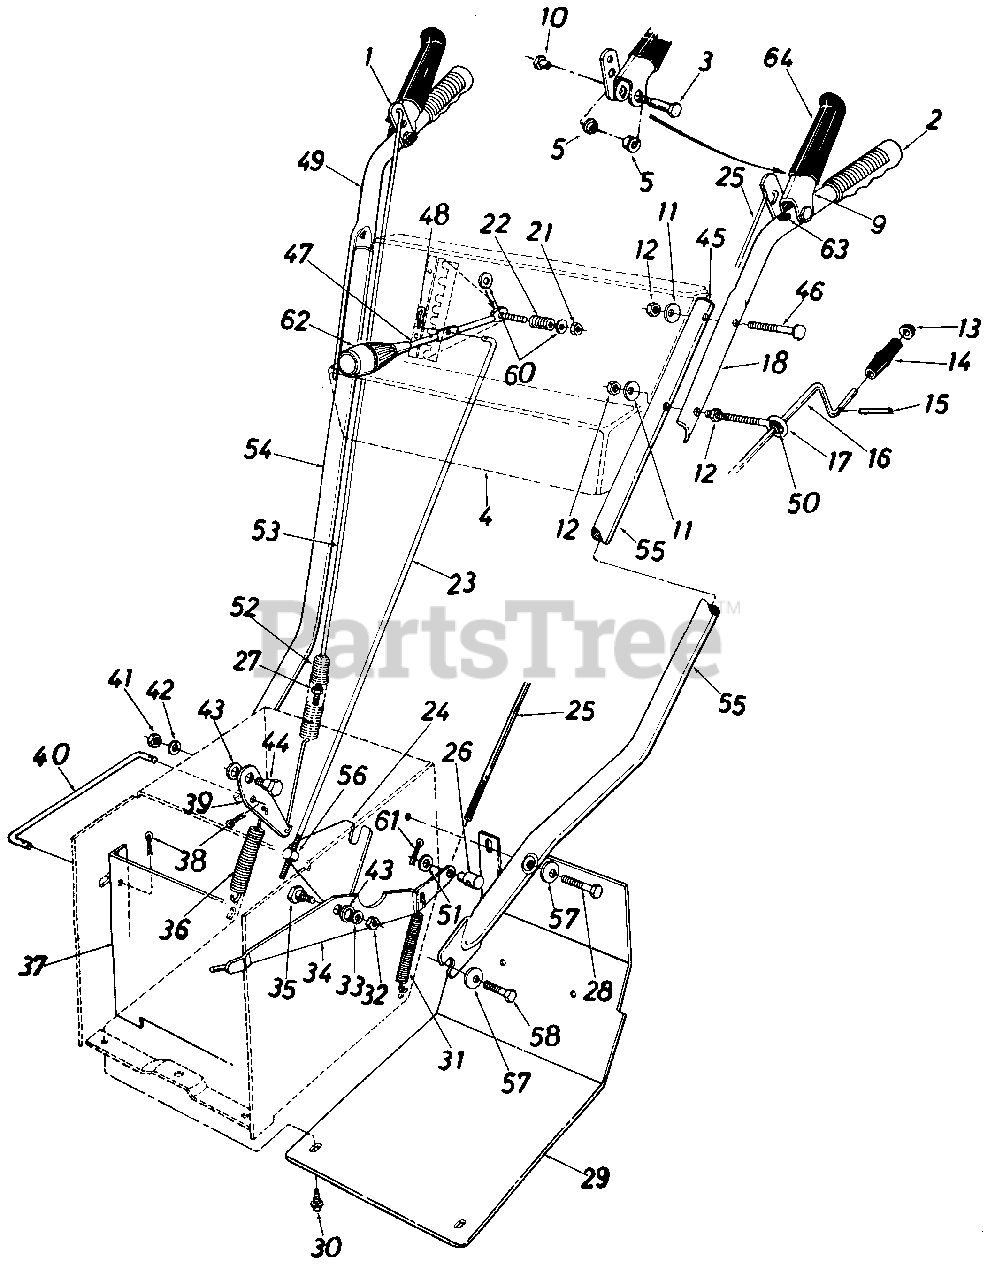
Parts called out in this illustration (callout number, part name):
1	Clutch Grip Ass'y.-R.H.
3	Shoulder Bolt .374 Dia. x 1.375" Lg.
4	Handle Panel Ass'y.
5	Hex Flange Plastic Bearing .380" I.D.
9	Clutch Grip Ass'y.-L.H.
10	Shoulder Nut 1/4-20 Thd.
11	Bell-Wash. .34" I.D. x .88" O.D.
12	Hex Nut 5/16-18 Thd.
13	Push Nut 318" Rod
14	Knob 318" Rod
15	Roll Pin .12 Dia. X .63" Lg.
16	Chute Crank Ass'y. 39" Lg.
17	Eye Bolt 5/16-18 x 5.0" Lg.
18	Upper Handle-L.H. (Painted)
21	Hex Ins. Jam L-Nut 5/16-18 Thd.
22	Compression Spring .50" O.D. x .88" Lg.
23	Shifting Rod 5116" x 32.50" Lg.
24	Shifting Linkage Bracket
25	Lockout Rod .214" Dia. x 36.0" Lg.
26	Adjustment Ferrule 1/4-20
27	Hex Ins. L-Nut 1/4-20 Thd.
28	Hex Bolt 3/8-16 x 2.00" Lg.
29	Frame Cover
30	Hex Wash. Self-Tap Scr. 1/4-20 x .50" Lg.
31	Extension Spring .38" O.D. x 3.25" Lg.
32	Hex Jam Nut 3/8-16 Thd.
33	L-Wash. 318" I.D.
34	Auger Clutch Bracket Ass'y.
35	Shld. Bolt .6251 Dia. x .170
36	Extension Spring .75' O.D. X 4.31 Lg.
37	Drive Pulley Support Brkt. Ass'y.
38	Cotter Pin 3/32" Dia. x .75" Lg.
39	Drive Clutch Bracket
40	Drive Clutch Rod
41	Hex Jam Nut 3/8-16 Thd.
42	L-Wash. 3/8 I.D.
43	Bell-Wash. .40" I.D. x 1.13" O.D.
44	Shld. Bolt .625' Dia. x .170
45	Plastic Plug
46	Carriage Bolt 5/16-18 X 2.0 Lg.
47	Shift Handle
48	Int. Cotter Pin 5/16" Dia.
51	Fl-Wash. .344n l.D. x .62 O.D.
52	Extension Spring .75" O.D. x 5.00" Lg.
53	Lockout Rod .214 Dia. x 32' Lg.
54	Lower Handle-R.H. (Painted)
55	Lower Handle-L.H. (Painted)
56	Adjustment Ferrule
57	Bell-Wash. .40" I.D. x .88" O.D.
58	Hex Wash. Self-Tap Scr. 3/8-16 X .75 Lg.
60	Fl-Wash. .344 I.D. x .62n O.D.
61	Cotter Pin 3/32" Dia.
63	Push Cap
64	Black Vinyl Grip
